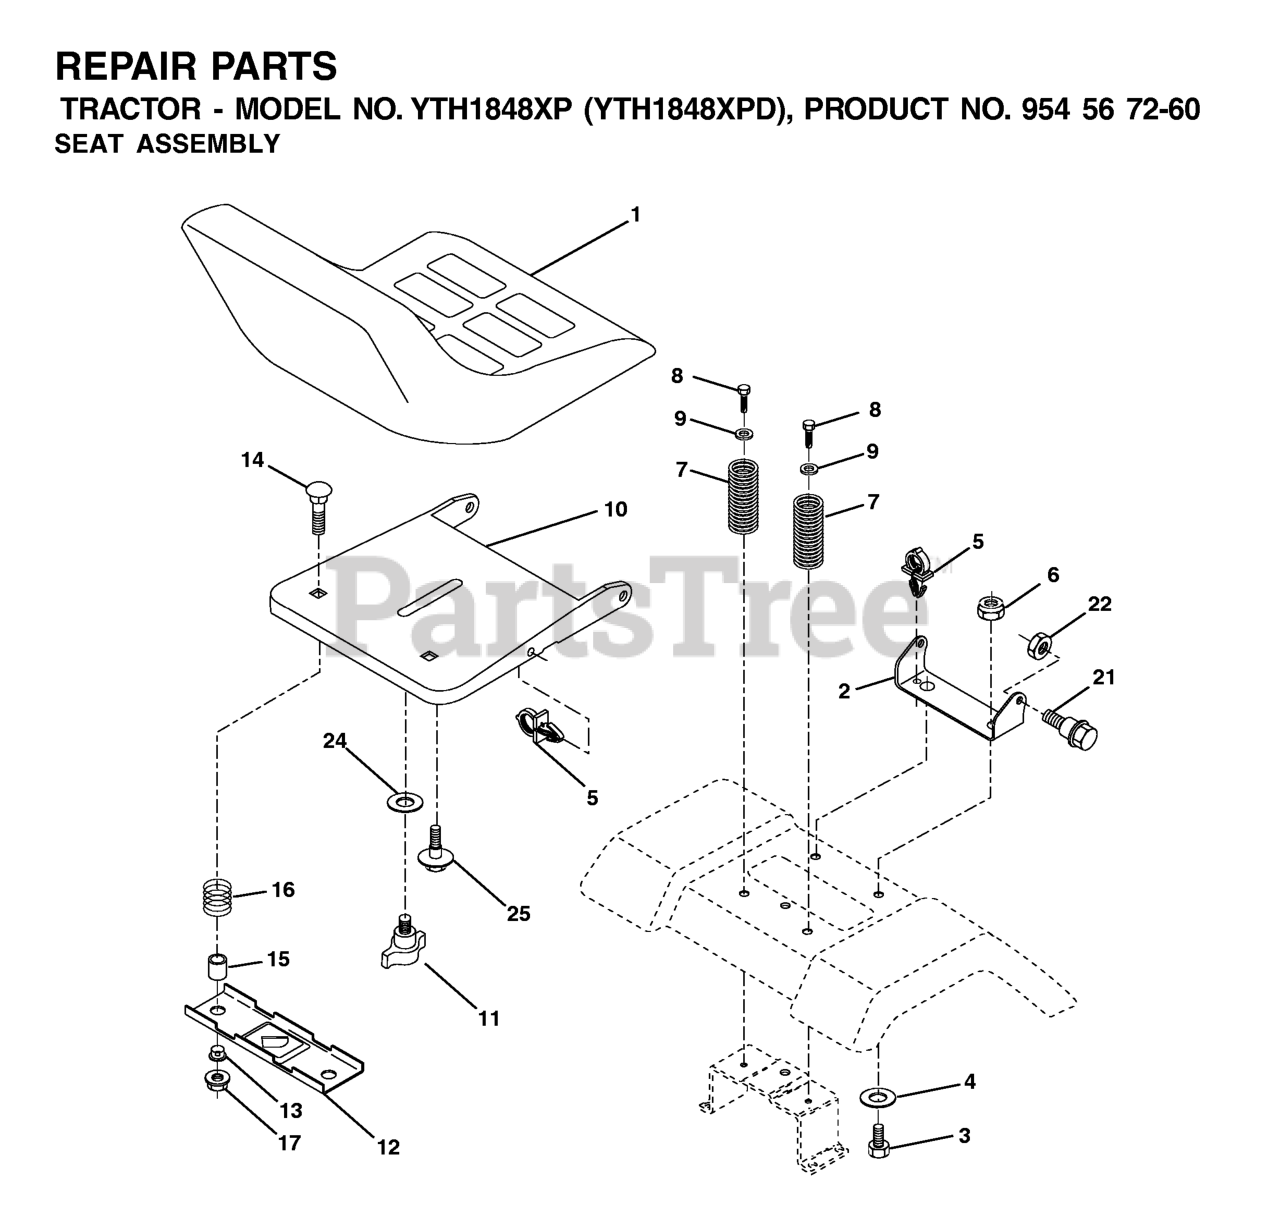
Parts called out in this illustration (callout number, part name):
1	SEAT, GRAY
2	SEAT PIVOT BRKT
3	BOLT, HEX 3/8-16X1
6	NUT
7	SPRING COMPRESSION
8	SCREW 3/8-16X1
9	WASHER
10	PAN, SEAT
11	KNOB.SEAT.ADJ.WINGNUT
12	BRKT SWITCH
14	BOLT.ROUND.HEAD.SQUARE.NECK
15	SPACER SPLIT
16	SPRING COMPRESSED
17	NUT T
21	BOLT.SHOULDER.5/16-18
22	NUT.71038.31-18.HEX.NYLOCK
25	BOLT,SHOULD
